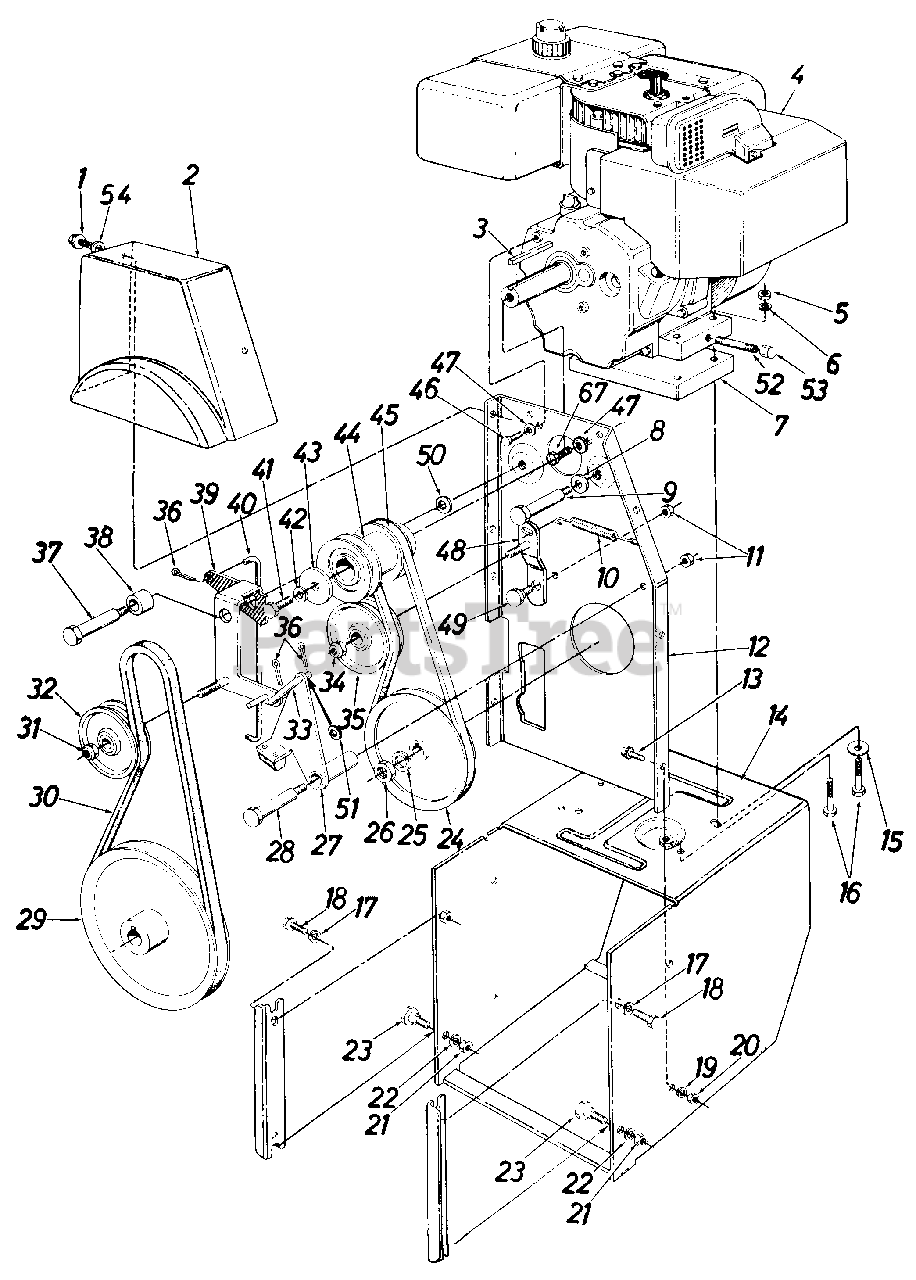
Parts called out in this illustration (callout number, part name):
1	Hex Wash. Self-Tap Scr. 5/16-24 x .50" Lg.
2	Belt Cover
3	Sq. Key 1/4" X 1.50" Lg.
4	Engine
5	Hex Nut 5/16-18 Thd.*
6	L-Wash. 5/16" Scr.*
7	Engine Spacer Ass'y.
8	Bell-Wash. .40 I.D. x .88 O.D.
9	Shld. Scr. .498" Dia. x 3.00" Lg .
10	Ext. Spring .38 O.D. x 3.18"-Lg.
11	Hex Cent. L-Nut 3/8-16 Thd.
12	Engine Brkt. Ass'y.
13	Hex Sems Scr. 5/16-18 x .75" Lg.*
14	Frame Ass'y.
15	Fl-Wash. .345 I.D. x .75 O.D. x .060
16	Hex Scr. 5/16-18 x 2.50" Lg.
17	L-Wash. 3/8" Scr. H.D.
18	Pilot Scr. 3/8-16 x .88" Lg.
19	L-Wash. 5/16" Scr.
20	Hex Nut 5/16-18 Thd.
21	Hex Nut 3/8-16 Thd.*
22	L-Wash. 3/8" Scr. H.D.
23	Shld. Scr. .498" Dia. x .340"-Lg.
24	V-Puiley .628 I.D. x 7.50 O.D.
25	L-Wash. for 5/8" Scr.*
26	Hex Ins. Jam L-Nut 5/8-18 0 Thd.
27	Brake Brkt. Ass'y.
28	Shld. Scr. .498" Dia. x 2.00" Lg.
29	V-Pulley .875 I.D. x 10.12 0 O.D.
30	"V"-Belt
31	Hex Ins. Jam L-Nut 3/8-24 Thd.
32	Fl-Idler w/Flanges 3.0 O.D.
33	Brake Linkage Ass'y.
34	Hex Ins. Jam L-Nut 3/8-24 Thd.
35	3.0" O.D. Fl-Idler w/Flanges
36	Int. Cot. Pin 5/16" Dia.
37	Shld. Scr. .625 Dia. x 2.750" Lg.
38	Spacer .75 O.D. x 1.00" Lg.
41	Hex Bolt 3/8-24 x 1.25" Lg.
42	L-Wash. 3/8" Scr. H.D.
44	Engine Pulley-Double Groove
45	"V"-Belt
46	Hex Scr. 5/16-24 x .62" Lg.
47	Bell-Wash. .345 I.D. x .88 O.D. x .060
48	Drive Idler Brkt. Ass'y.
49	Shld. Scr.-.625" Dia. x .170" Lg.
50	Bell-Wash. .40 I.D. x 1.12 0 O.D.
51	Fl-Wash. .34 I.D. x .750 O.D. x .05
52	Pipe Nipple-1/2" Pipe Thd. x 3.00" Lg.
53	Hex Scr. 1/4-18 Pipe Thd.
54	Fl-Wash. .340 I.D. x .62 O.D. x .62
